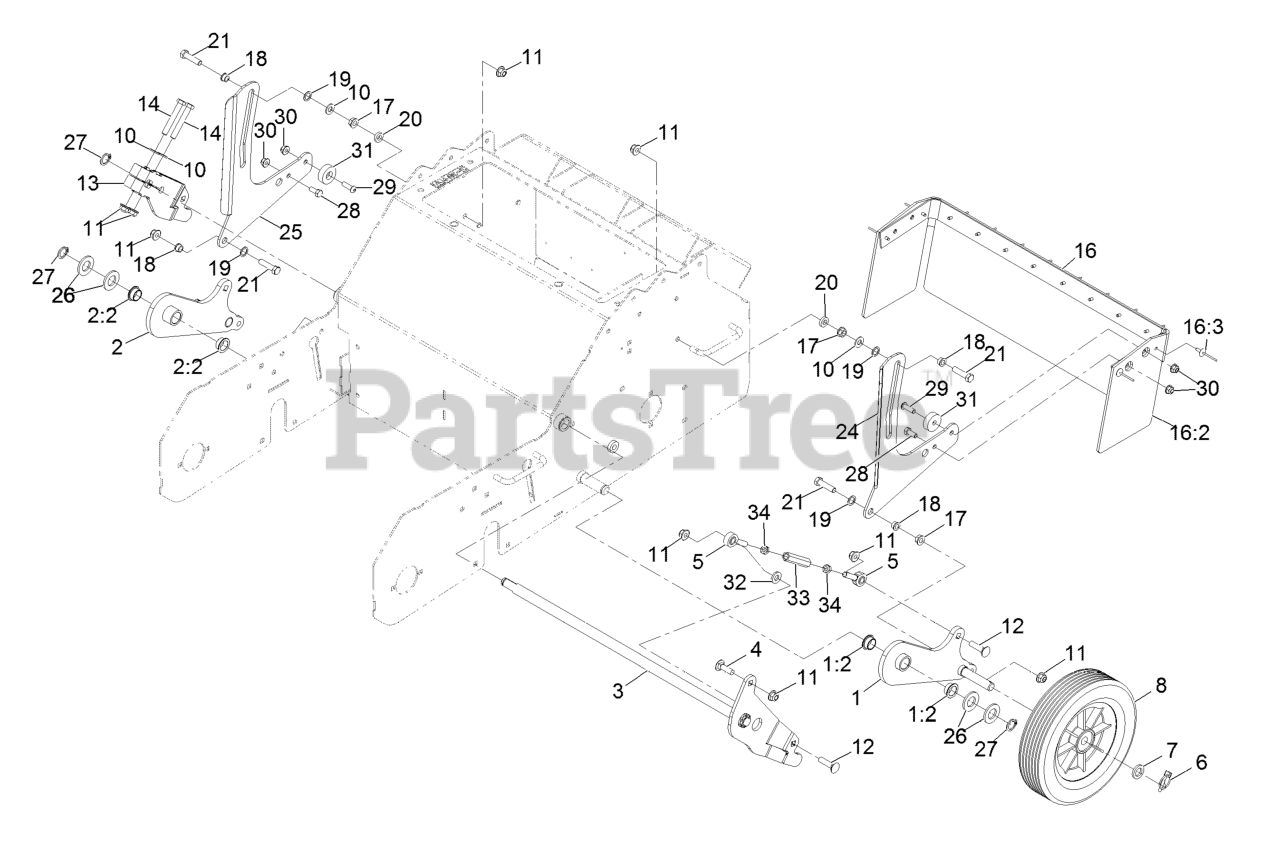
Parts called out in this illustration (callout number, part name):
1	WHEEL ARM ASM-LH W/BRGS
1:2	BUSHING-BRONZE
2	WHEEL ARM ASM-RH W/BRGS
2:2	BUSHING-BRONZE
4	BOLT-CARR
5	BALLJOINT
6	PIN-KLIK
7	SPACER-BEARING
8	WHEEL-TRANSPORT 10"
10	WASHER-FLAT
11	NUT-HF, NI
12	SCREW-CARR
13	ARM-LIFT, RH
14	BOLT-CARR
16	GUARD-FOOT
16:2	FOOT-SHIELD
16:3	RIVET-POP
17	NUT-HHF, WHIZ
18	BUSHING-FLANGED
19	WASHER-NYLON
21	SCREW-HH
24	GUARD-ARM, LH
25	GUARD-ARM, RH
26	WASHER-FLAT
27	RING-RETAINING
28	SCREW-HH
29	SCREW-HSBH
30	NUT-HF, NI
31	GUIDE-ARM, TRAIL
33	ROD-LIFT LINK
34	NUT-HJ
